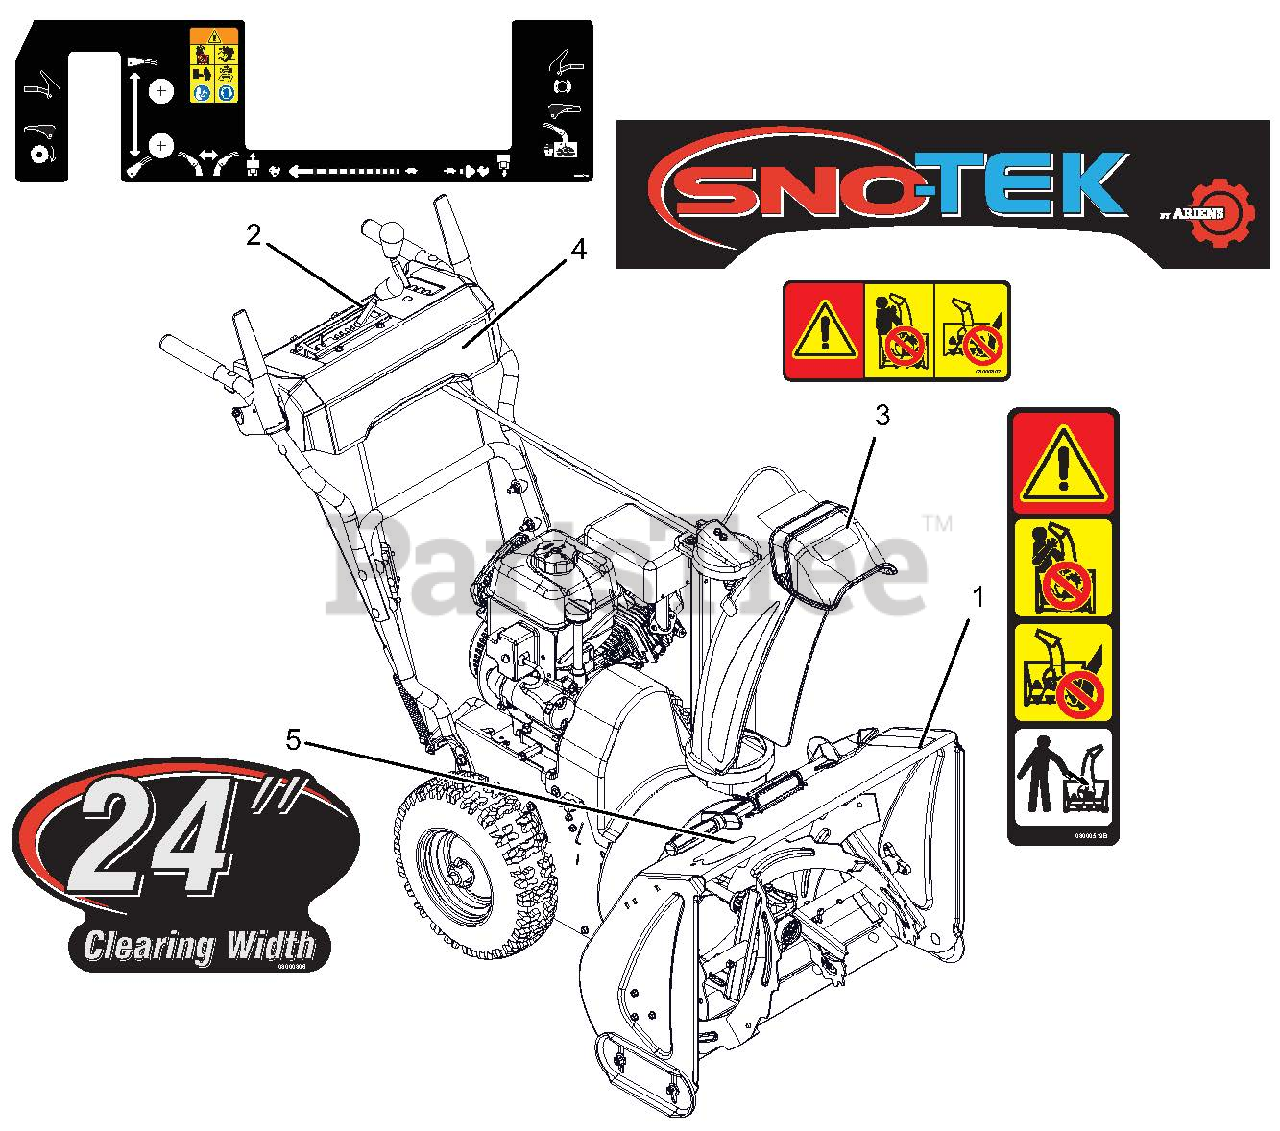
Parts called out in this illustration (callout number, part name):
1	DECAL, DANGER - ROTATING PARTS
2	DECAL,CONTROL - COMPACT REMOTE
3	DECAL, DANGER SNO-TEK
4	DECAL, DASH - SNO-TEK
5	DECAL, HOUSING SNO-TEK 24
